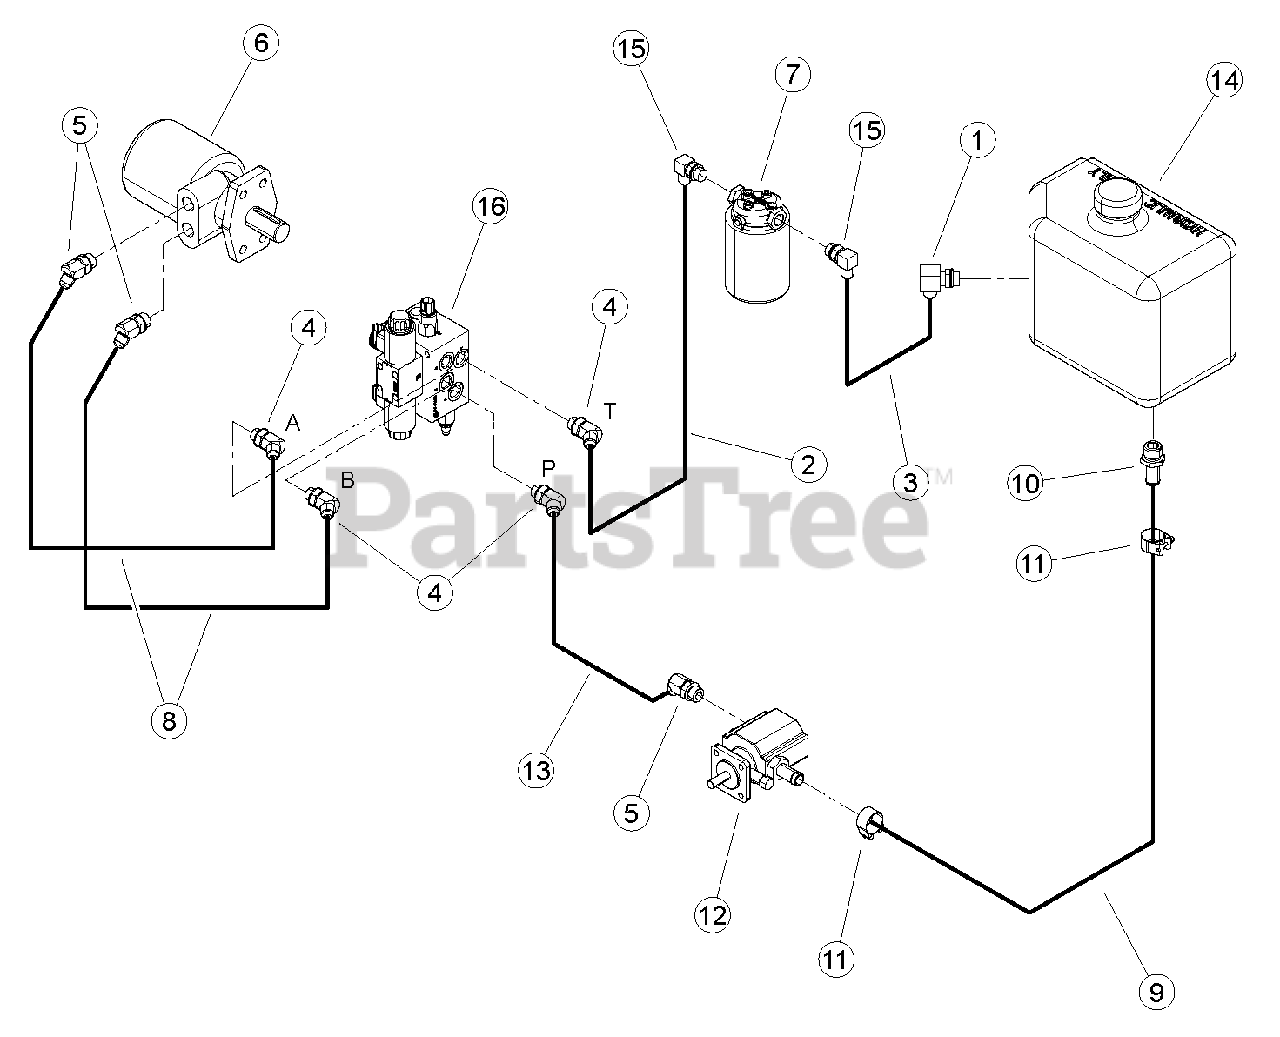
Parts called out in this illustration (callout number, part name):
1	ADAPTER, -10MORING/-8MJIC 90 DEG
2	HYD. HOSE ASSEMBLY., 2X-8FMJICSW
3	HOSE ASSEMBLY, 8FMJIC/8FMJIC SW X 32"
4	ADAPTER, -8MORB/-8MJIC 45
5	ADAPTER, -10MORING/-8MJIC 45 DEG
6	MOTOR, 45 CU IN HYDRAULIC
7	ASSEMBLY, HYDRAULIC FILTER
8	HOSE, .375 X 36 -8FMJIC/-8FMJIC
9	HOSE, .75 ID X 21 IN 100R4 HYD
10	ADAPTER, -10 MORB/-12 HOSE BARB
11	CLAMP, 1-5/32 TO 7/32 OD RANGE T-BOLT
12	PUMP, 2 STAGE CW HI/LO 0.605 DISP.
13	HOSE, .50 X 48 -8FMJIC/-8FMJIC
14	TANK, HYDRAULIC
15	ADAPTER, -8MORING/-8MJIC 90 DEG
16	ASSEMBLY, HYDRAULIC FEED FLOW VALVE W/ PS
